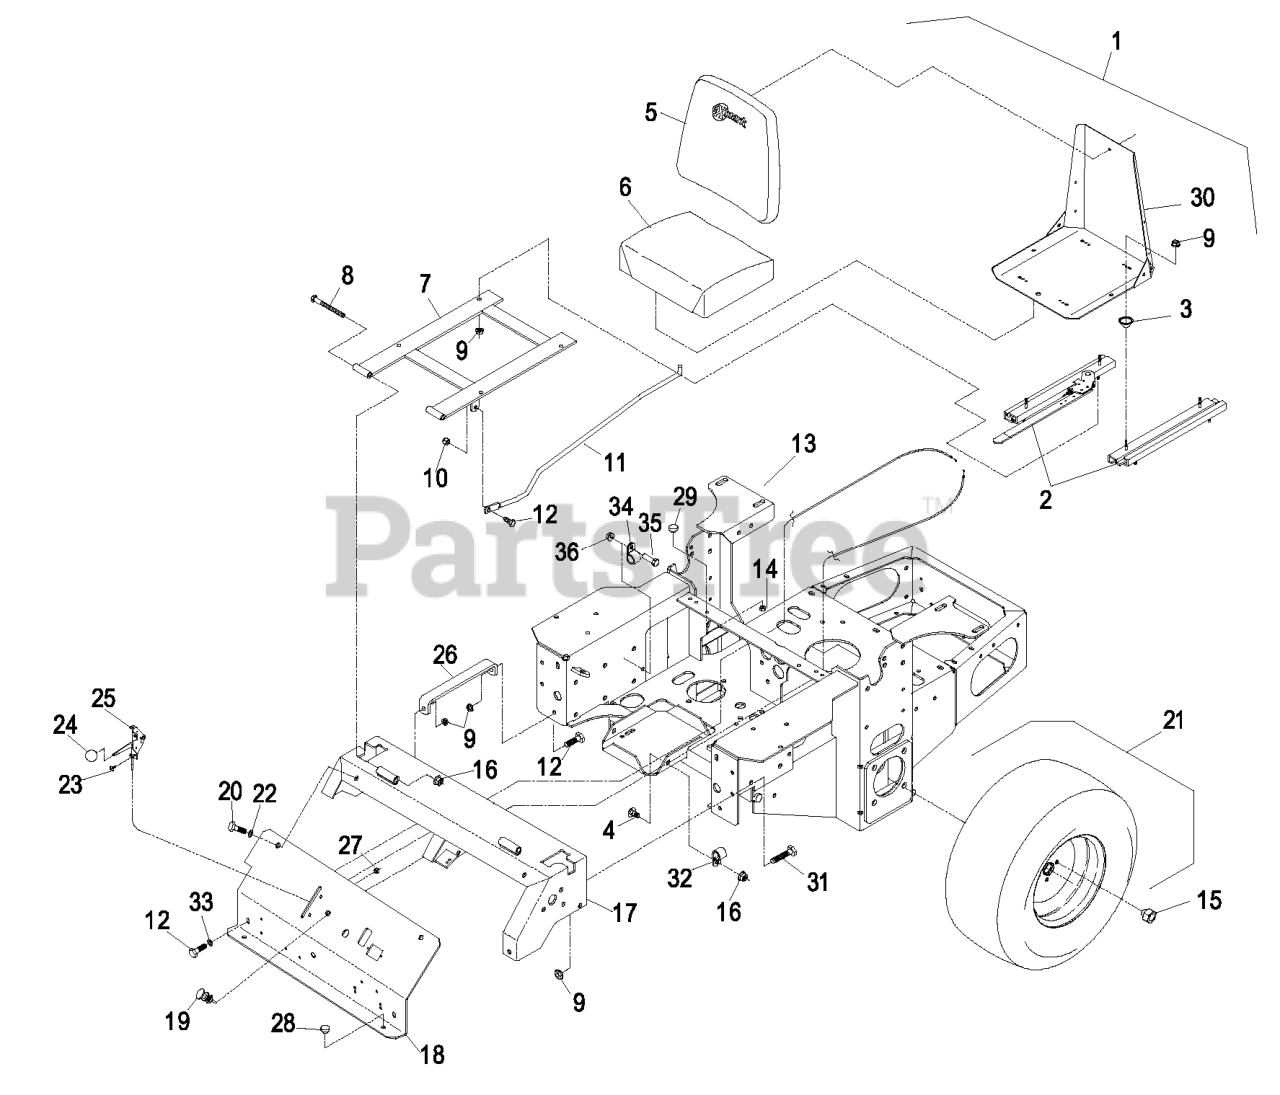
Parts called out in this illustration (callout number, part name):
2	TRACK-SEAT
3	SPACER-TRACK
4	SCREW-CARR
8	SCREW-HH
10	NUT-LOCK, NI
11	ROD-RETAINER, SEAT
12	SCREW-HH
14	NUT-LOCK, NI
15	NUT-LUG
16	NUT-LOCK, NI
17	ASM,CONSOLE WELDMENT W/DE
19	CONTROL-CHOKE
20	SCREW-HH
21	WHEEL AND TIRE ASM
22	WASHER-PLAIN
23	BOLT-CARR
24	KNOB-BALL
25	CABLE-THROTTLE
27	NUT-LOCK, NI
30	FRAME-SEAT
31	SCREW-HH
32	CLIP-LOOM
33	WASHER-FLAT
34	CLIP-LOOM
35	SCREW-HH
